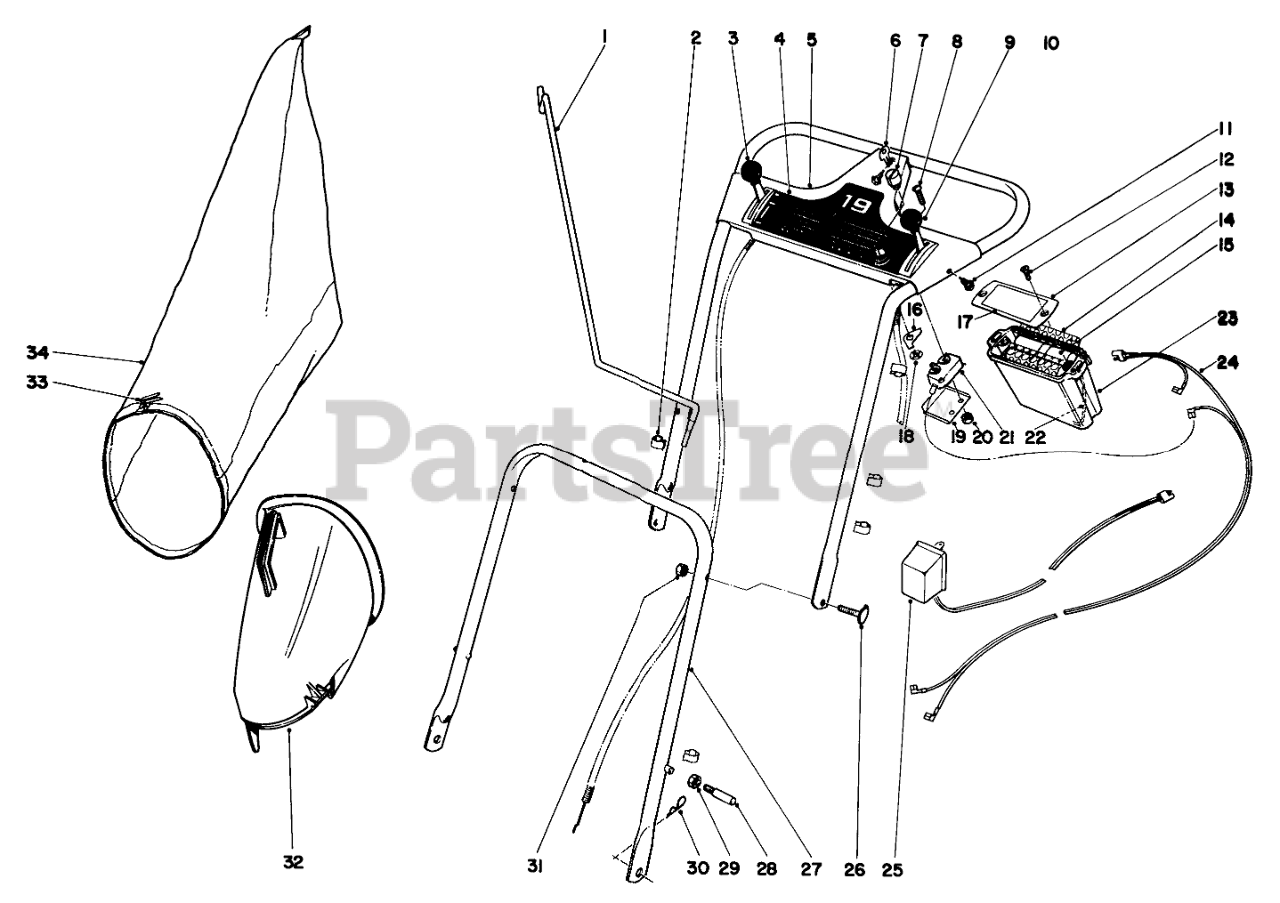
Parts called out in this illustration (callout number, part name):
1	Bag Hanger Rod
2	CONTROL WIRE CLIP
3	Control, Throttle
4	Decal, Escutcheon Plate
5	Escutcheon Plate
7	Key Hsg.
9	Traction Control
10	Upper Handle
11	SCREW-HWHTF
13	Cover
14	Spacer
15	Battery Pack
17	Decal
19	Cover Switch
20	NUT-KEPS
21	Switch
22	Plug & Wire
23	Container Pack
24	Wire Harness
25	Charger
26	1-1/4 LG HANDLE SCREW
27	Lower Handle
28	Handle Pin
29	INSERT-THREADED
30	PIN-COTTER, HAIR
31	Nut
32	Bag Attachment
33	BAG CORD FASTENER
34	Grass Bag Kit
